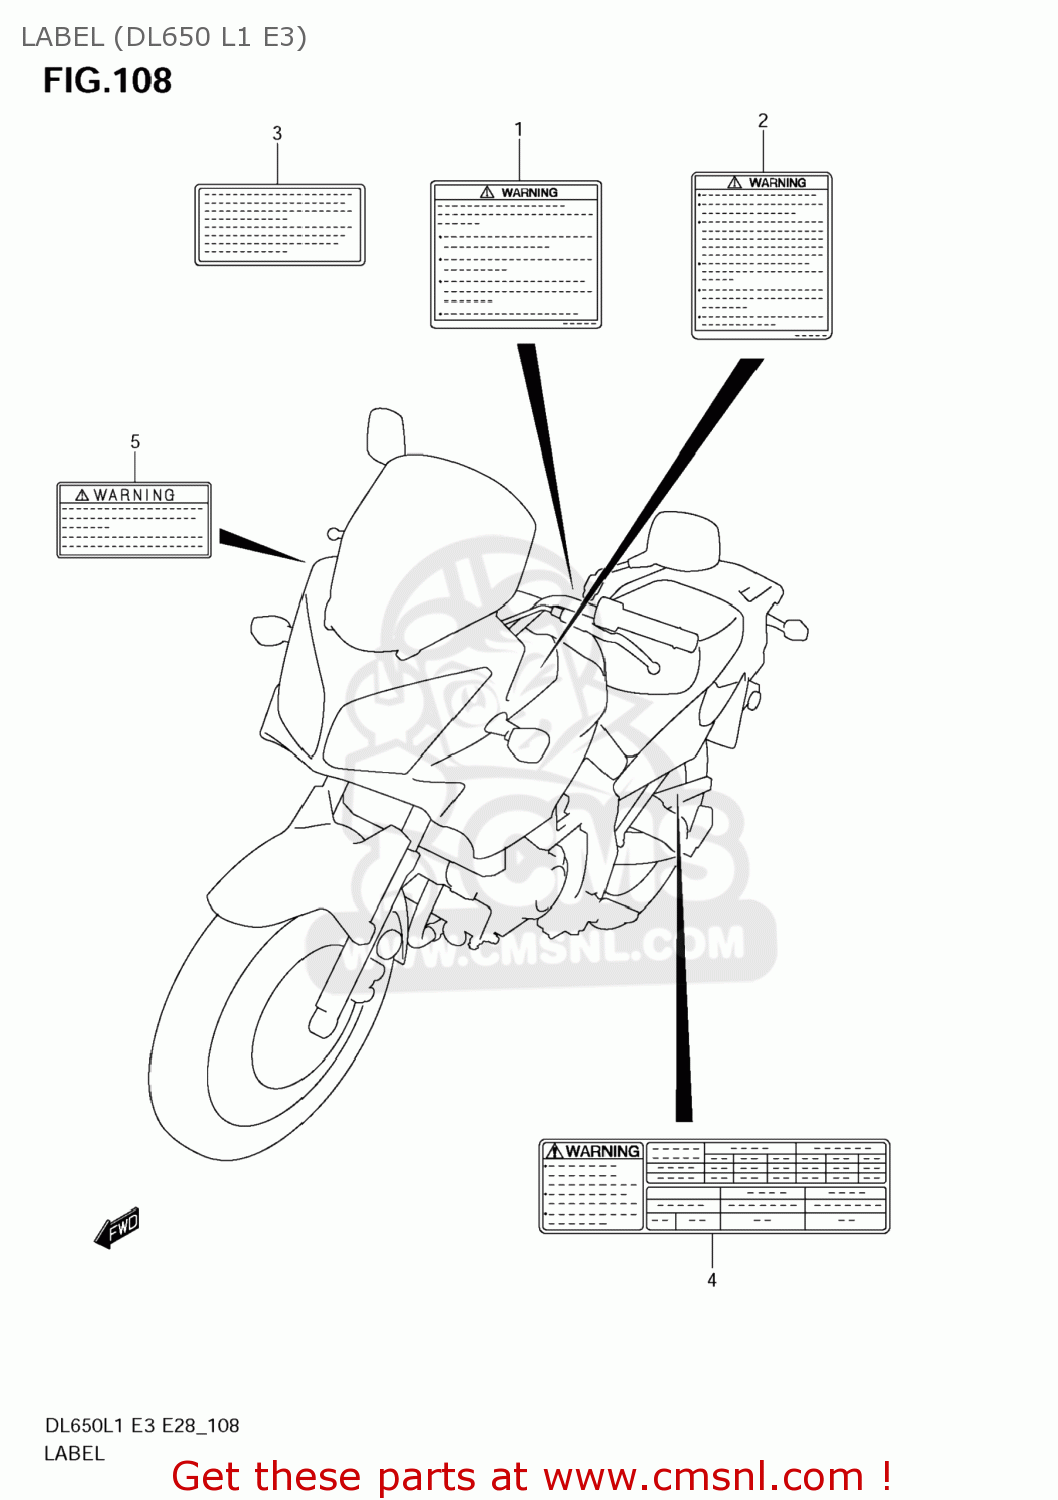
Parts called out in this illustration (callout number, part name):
1	LABEL,GENERAL WARNING
2	LABEL,SCREEN
3	LABEL,MANUAL NOTICE
4	LABEL,TIRE INFORMATION
5	LABEL,WARNING STEERING
6	MANUAL,OWNER'S
